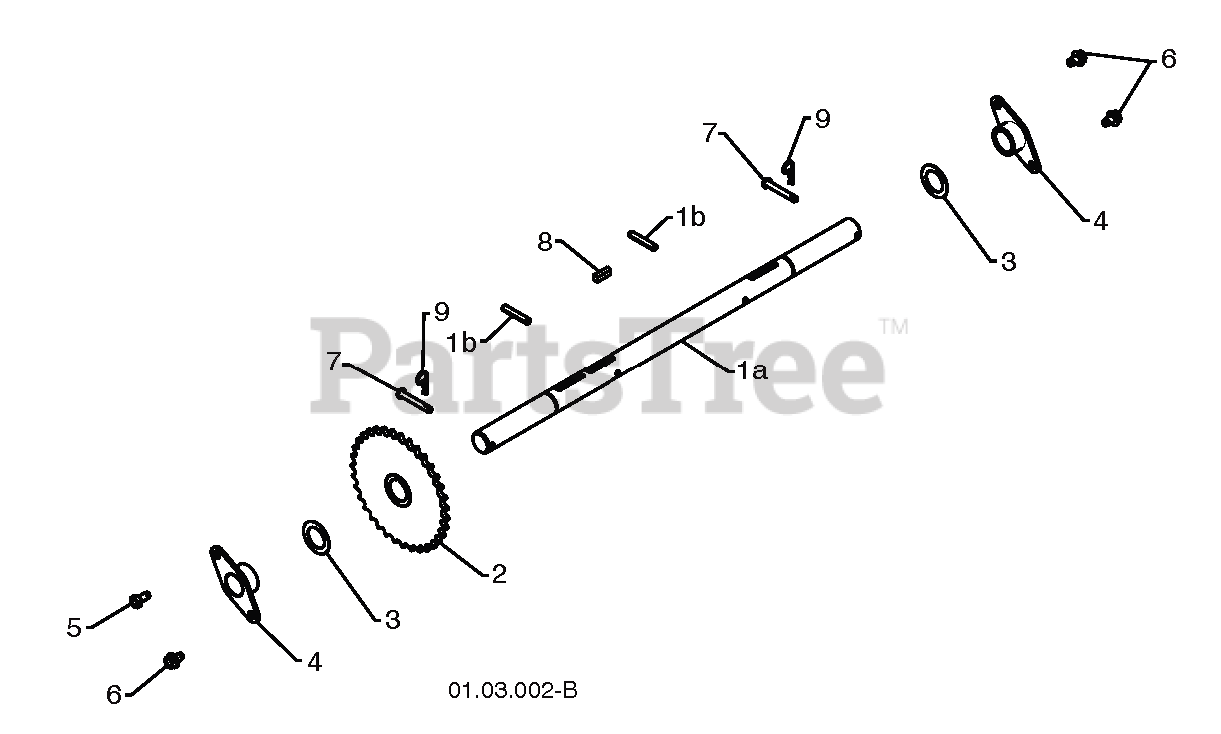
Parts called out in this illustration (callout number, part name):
1	AXLE.ASM.SHAFT.W/ROLLPIN.PS
2	SPROCKET.WELDMENT.AXLE.1.00
3	WASHER 1.00
4	BEARING, AXLE
6	Screw 5/16-18 x 1/2 Hex, Self Tapping 5/16-18 x 1/2
7	RIVET
8	KEY, SQUARE 1/4 X .875
9	RETAINER M
